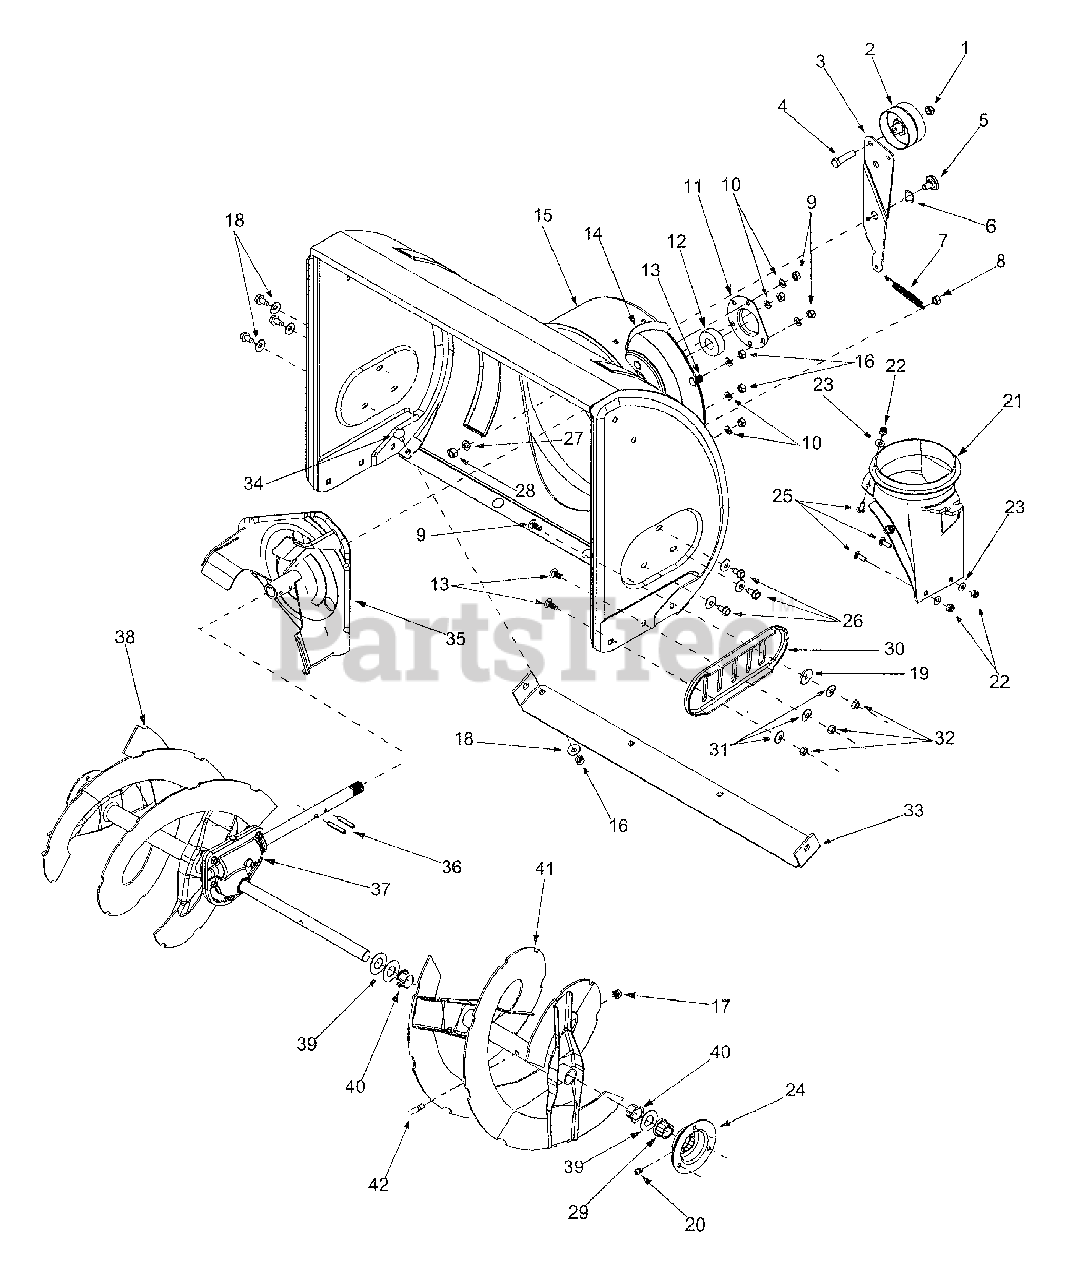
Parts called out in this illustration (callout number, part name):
1	Lock Jam Nut 3/8-24
2	Flat Idler
3	Auger Idler Arm
4	Hex Cap Screw 3/8-24 x 1.50
5	Shoulder Screw
6	Wave Washer
7	Extension Spring
8	Hex Nut 5/16-18
9	Carriage Bolt, 5/16-18 x 1.00
10	Lock Washer 5/16
11	Housing
12	Ball Bearing
13	Carriage Bolt, 5/16-18 x .75
17	Lock Nut 5/16-18
18	Belleville Washer
19	Flat Wshr, .344 ID x 1.125 OD
20	Grease Fitting, 3/16" Drive
21	Chute Adapter
22	Hex Lock Nut 1/4-20
23	Flat Washer
24	Bearing Housing w/Fitting
25	Carriage Screw 1/4-20 x .75
26	Hex Screw 5/16-18
27	Lock Washer 3/8
28	Hex Nut 3/8-16
29	Hex Flange Bearing
30	Skid Shoe
31	Bell Washer
32	Hex Nut 5/16-18
33	Shave Plate
34	Carriage Bolt 5/16-18 x .62
35	Impeller Assembly
36	Pin
37	26" Gear Ass'y
37	30" Gear Ass'y
38	26" Spiral RH
38	30" Spiral RH
39	Flat Washer
40	Flange Bushing
41	26" Spiral LH
41	30" Spiral LH
42	Shear Bolt 5/16-18 x 1.5
